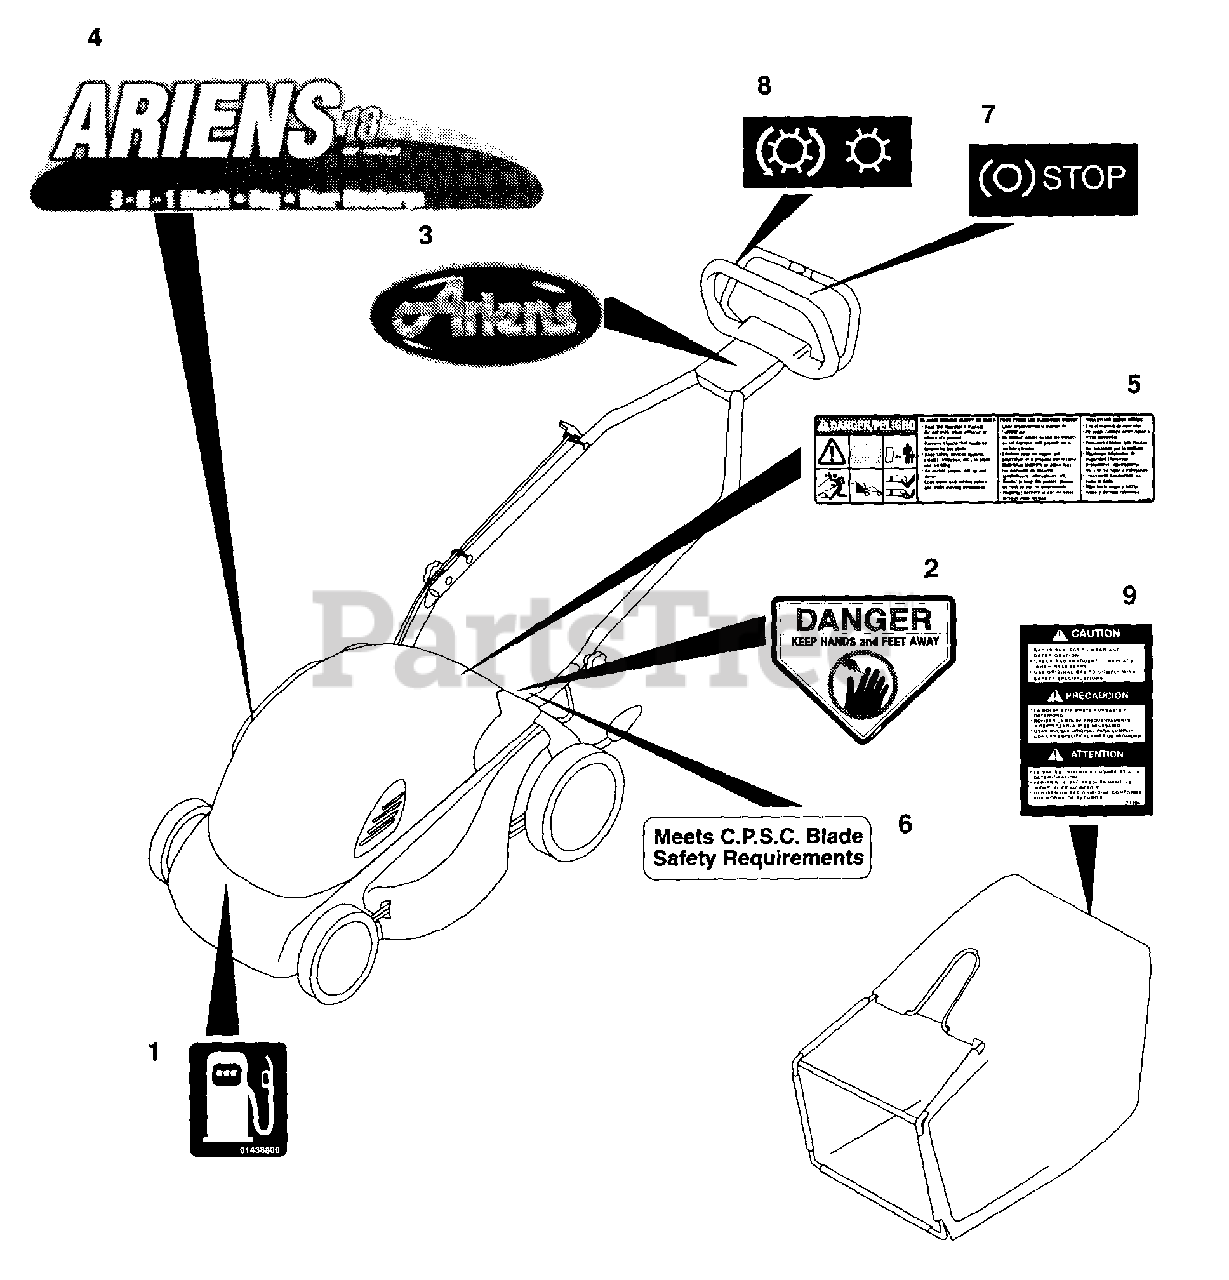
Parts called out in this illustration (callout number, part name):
1	DECAL, FUEL
2	DECAL, DANGER
3	DECAL, ARIENS MEDALLION
4	DECAL, LM18S
5	DECAL, CPSC DANGER REAR DOOR
6	DECAL, C.P.S.C. BLADE SAFETY
7	DECAL, ENGINE STOP OPC
8	DECAL, DRIVE
9	LABEL - BAGGER 21"
